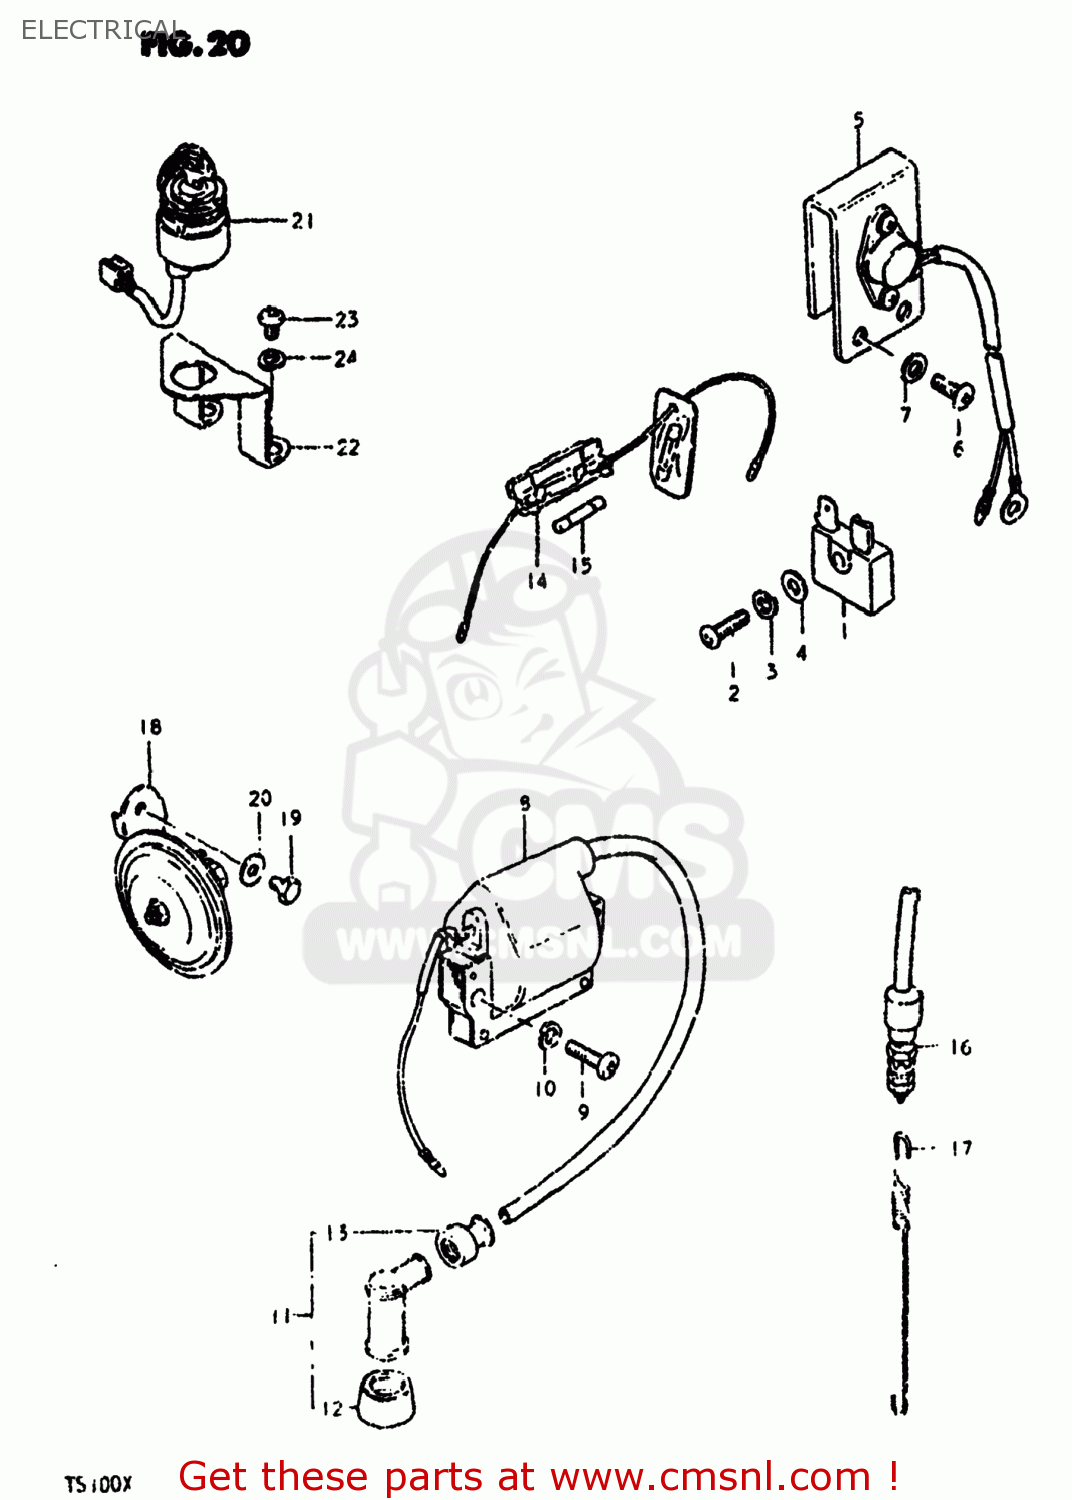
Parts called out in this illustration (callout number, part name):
1	RECTIFIER ASSEMBLY
2	SCREW 5X20
3	LOCK WASHER
4	WASHER
5	REGULATOR ASSEMBLY
6	SCREW 6X12
7	WASHER
8	UNIT & COIL ASSEMBLY,IGNITION
9	SCREW
10	LOCK WASHER
11	CAP,SPARK PLUG
12	SEAL,SPARK PLUG
13	SEAL,SPARK PLU
14	BOX ASSEMBLY,FUSE
15	FUSE(10A)
16	SWITCH ASSEMBLY,STOP LAMP
17	SPRING
18	HORN ASSEMBLY
19	BOLT
20	WASHER
21	SWITCH ASSEMBLY,IGNITION
22	BRACKET,IGNITION SWITCH
23	SCREW
24	LOCK WASHER
